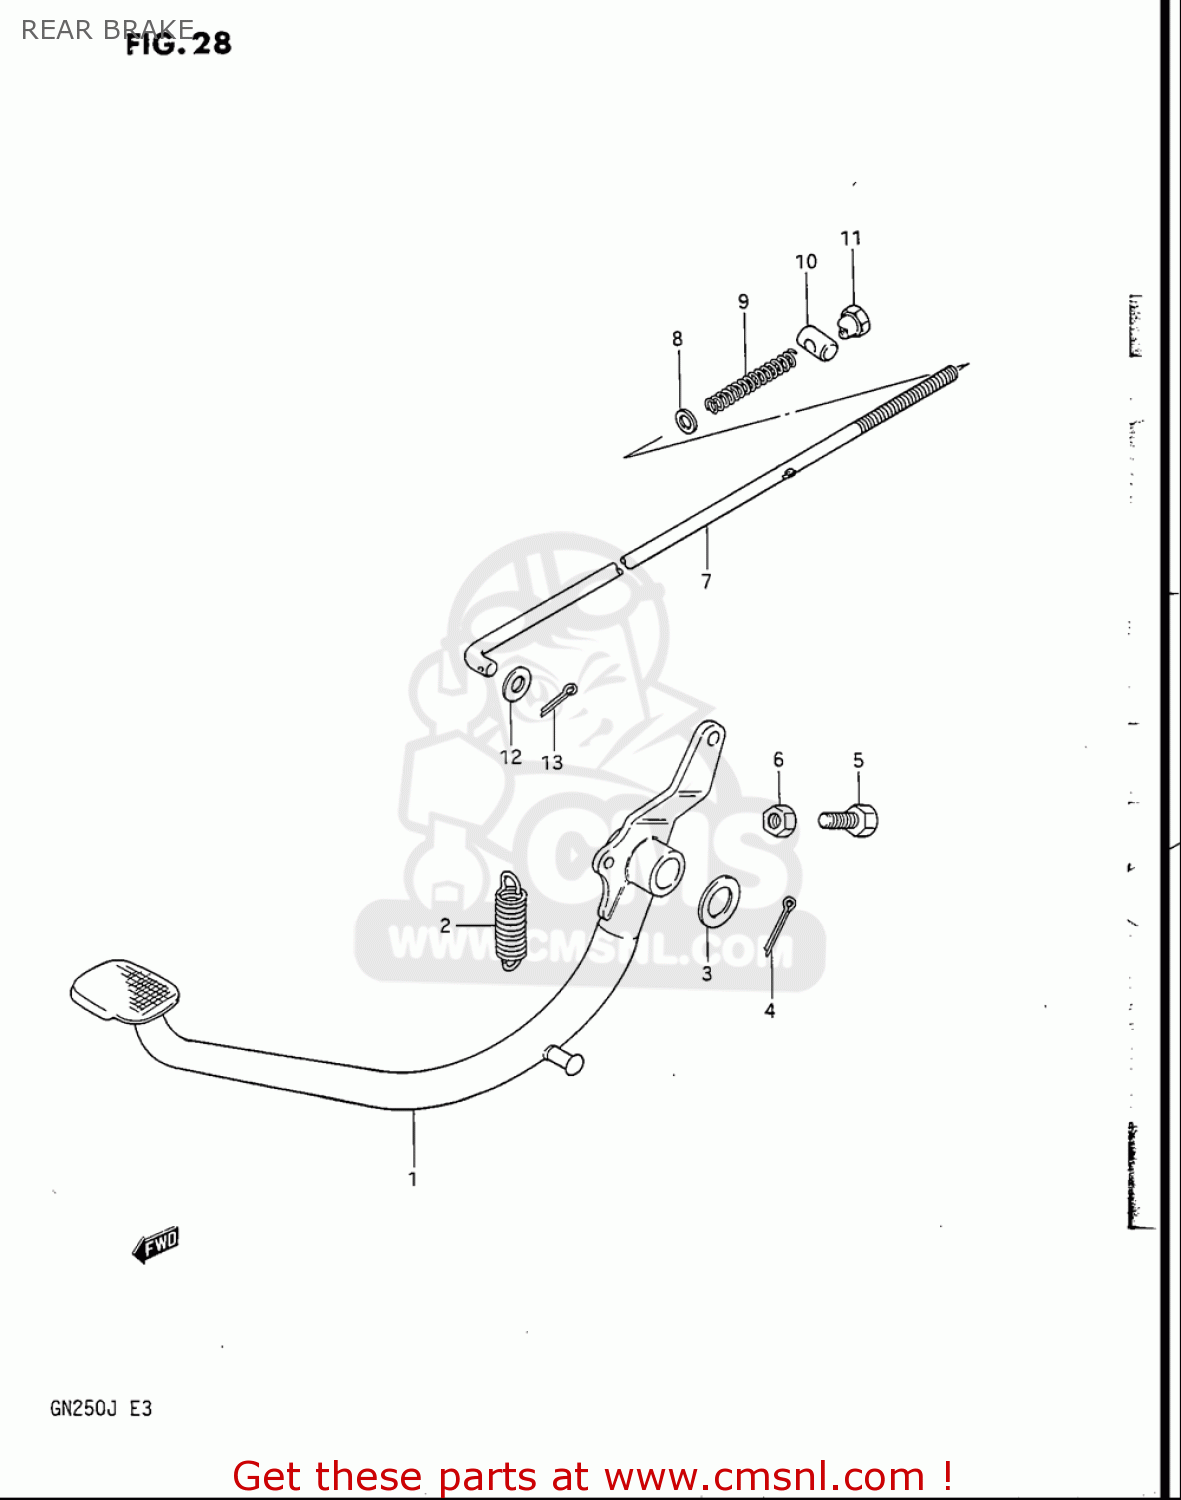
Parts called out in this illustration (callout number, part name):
1	PEDAL,BRAKE
2	SPRING
3	WASHER(15.5X26X2.3)
4	PIN
5	SCREW(6X23)
6	NUT
7	ROD ASSY,RR BRAKE
8	WASHER
9	SPRING
10	PIN(13X18)
11	NUT
12	WASHER
13	PIN
